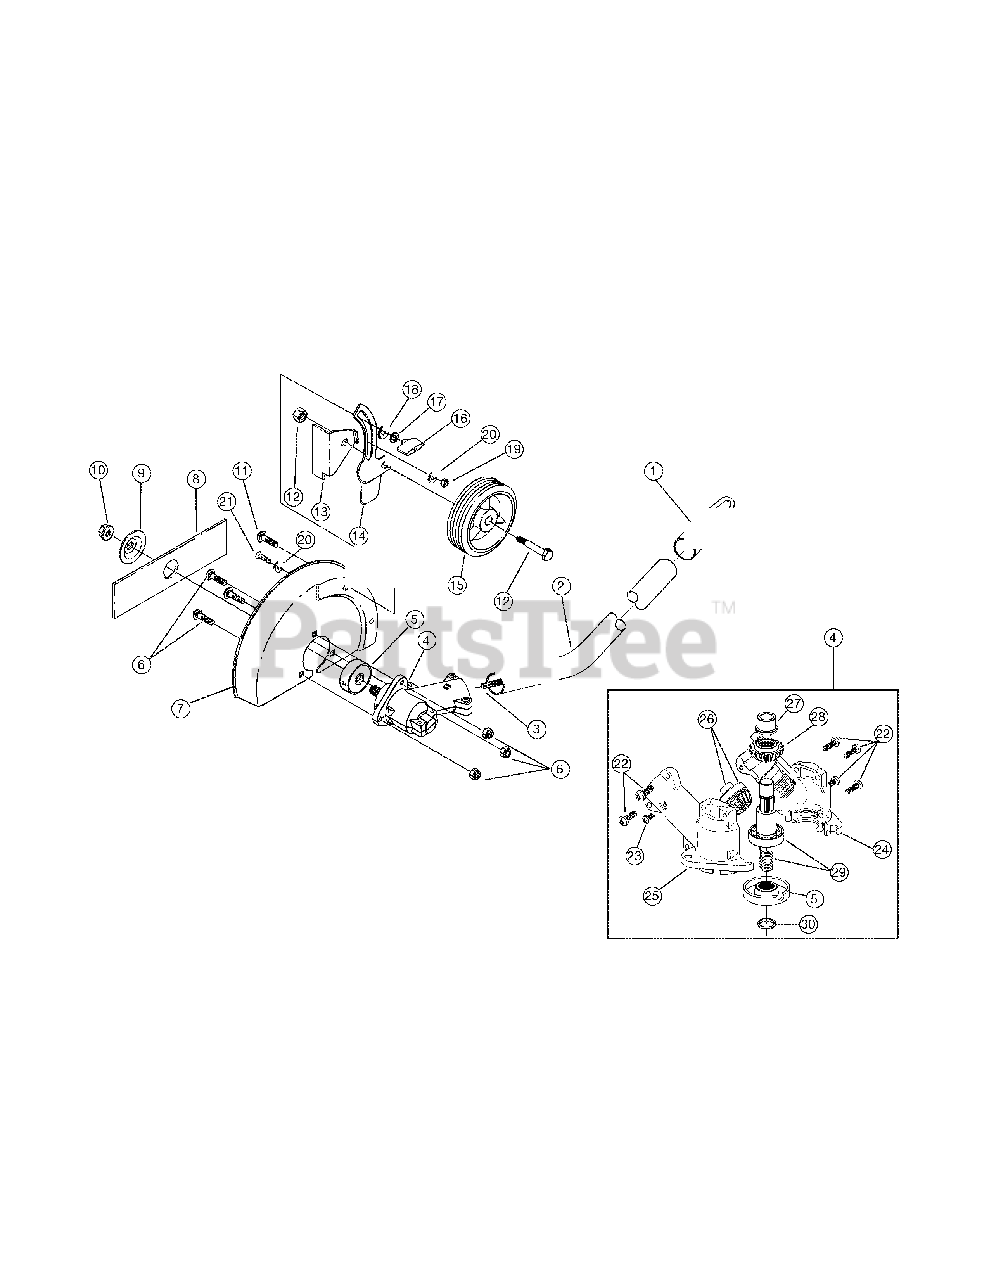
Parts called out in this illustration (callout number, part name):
1	Hanger
2	Drive Shaft Housing Assembly
3	Drive Shaft Assembly
4	Gearbox Assembly (includes 5, 6, 10, 19 & 20)
5	Blade Driver
6	Shield Mount Screw Assembly
7	Blade Shield
8	Edger Blade
9	Retaining Washer
10	Lock Nut
11	Shoulder Bolt
12	Wheel Mounting Hardware
13	Deflector
14	Guide Bracket
16	Adjustment Knob
17	Lock Washer
22	Gearbox Mounting Hardware
23	Anti-Rotation Screw
24	Left Housing
25	Right Housing
26	Pinion Gear Assembly
27	Output Shaft Bushing
28	Output Shaft Gear
29	Output Shaft Assembly (includes 27 & 28)
